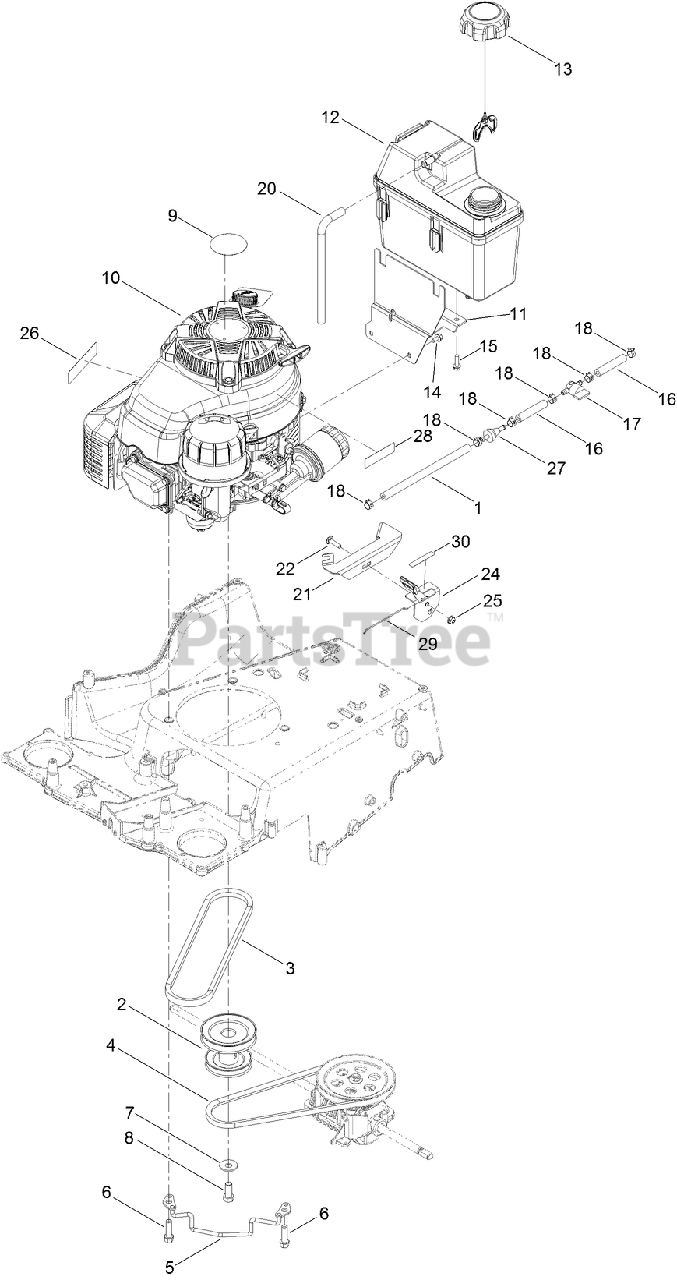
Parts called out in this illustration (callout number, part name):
1	HOSE-FUEL
2	PULLEY-ENGINE
3	V-BELT
5	GUIDE-BELT
6	SCREW-TAPTITE
7	WASHER-BELLEVILLE
8	SCREW-HH
9	Decal-Recoil
11	MOUNT-TANK
12	TANK-FUEL
13	CAP-FUEL
14	SCREW-HWH
15	SCREW-HWH
16	HOSE-FUEL
17	VALVE-FUEL
18	CLAMP-HOSE
20	HOSE-VENT, CANISTER
21	BRACKET-MOUNT, THROTTLE
22	SCREW-CARR
24	CONTROL-THROTTLE
25	NUT-HF
26	DECAL-ARRESTER, SPARK
27	FILTER-FUEL
28	DECAL-WARNING, ENGINE
29	WIRE-CONTROL
30	DECAL-THROTTLE, CHOKE
